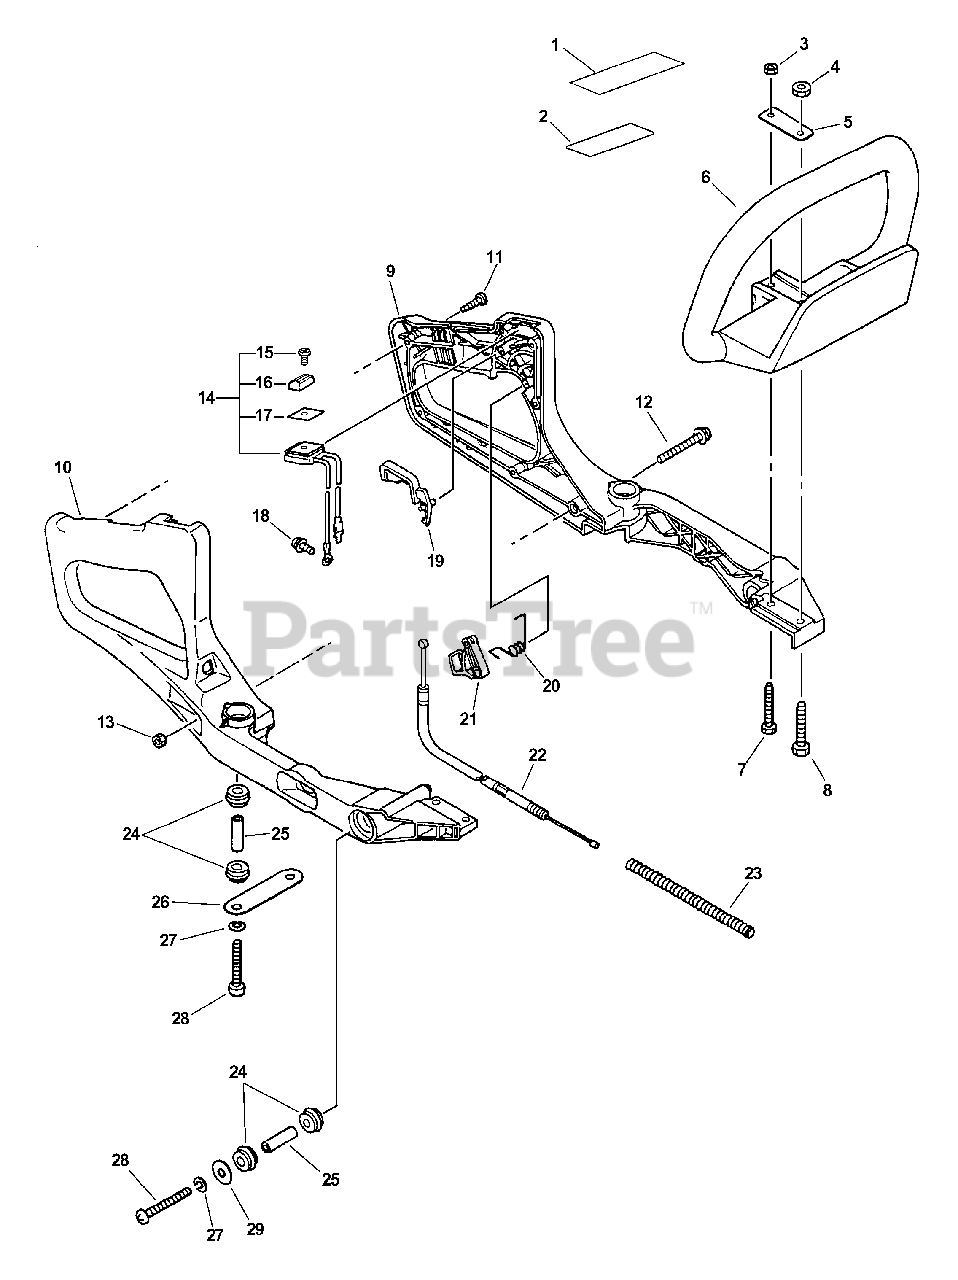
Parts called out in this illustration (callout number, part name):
1	LABEL - CAUTION
2	LABEL - CAUTION
4	LOCKNUT - 6
6	HANDLE - FRONT
7	BOLT - 5X35
8	BOLT - 6X32
9	HANDLE, REAR - LEFT
10	HANDLE, REAR - RIGHT
11	SCREW - 4X25
12	SCREW - 5X64
14	IGNITION SWITCH ASSY
15	SCREW - 3X10
16	KNOB, SWITCH - ORANGE
17	COVER, SWITCH - STOP
18	SCREW - 5X10
19	LOCKOUT, THROTTLE
20	SPRING, LOCKOUT LEVER
21	TRIGGER, THROTTLE
22	CABLE, THROTTLE
25	SPACER
27	LOCKWASHER - 5
28	SCREW - 5X40
